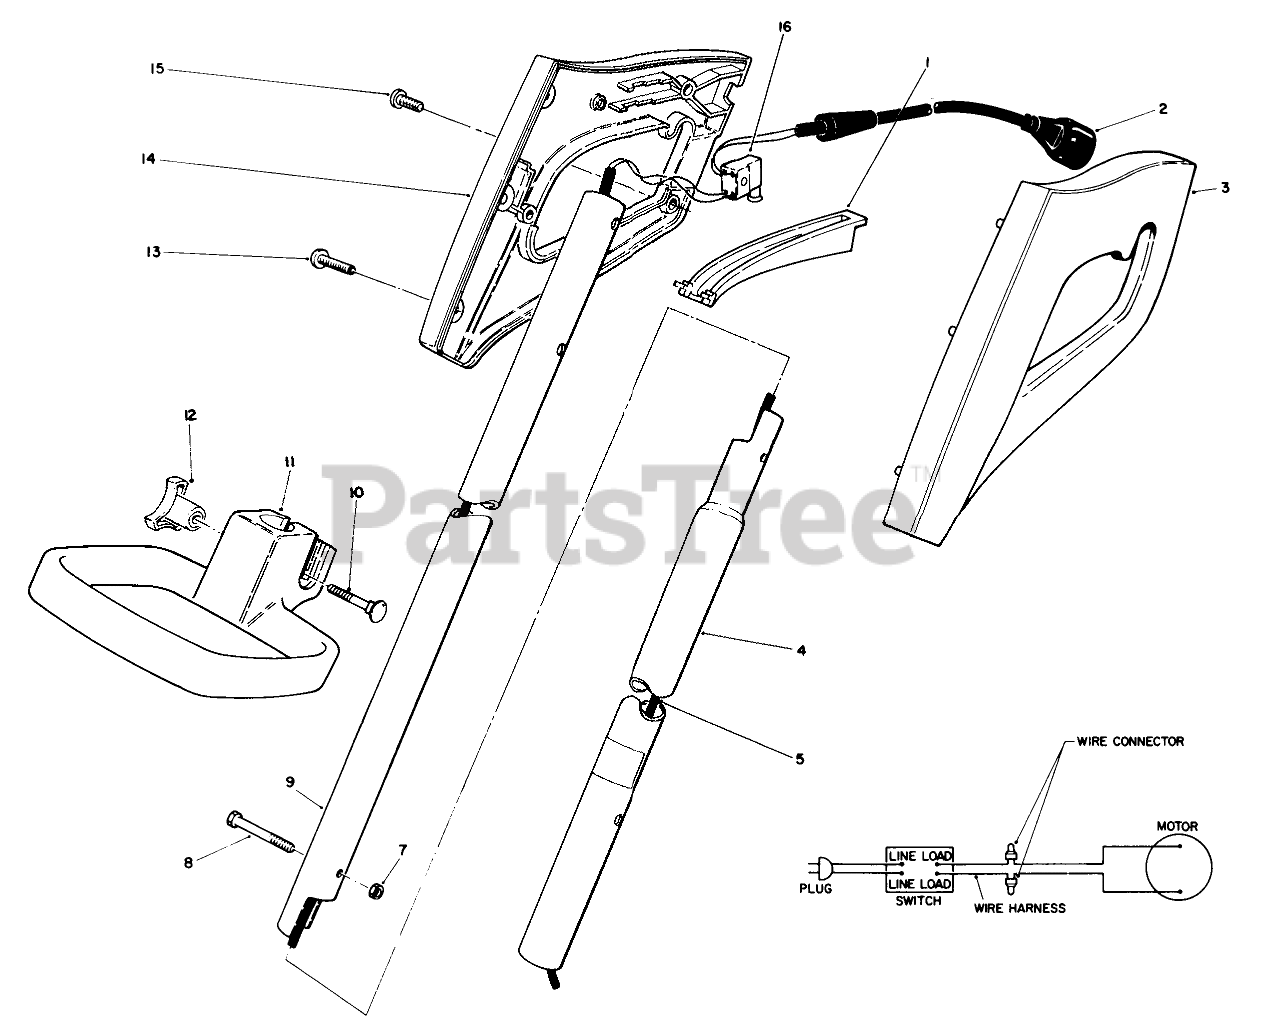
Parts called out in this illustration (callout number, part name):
1	TRIMMER-SWITCH BAR
2	Cord-Power
3	HANDLE GRIP, LH
4	Screw
5	Wire Harness
7	NUT-LOCK, NI
8	HEX HD MACHINE SCREW
9	TUBE-UPPER
10	BOLT-CARR
11	Handle-Adjust
12	HANDLE KNOB
13	Screw
14	HANDLE GRIP, RH
15	SCREW-PPH
16	SWITCH
